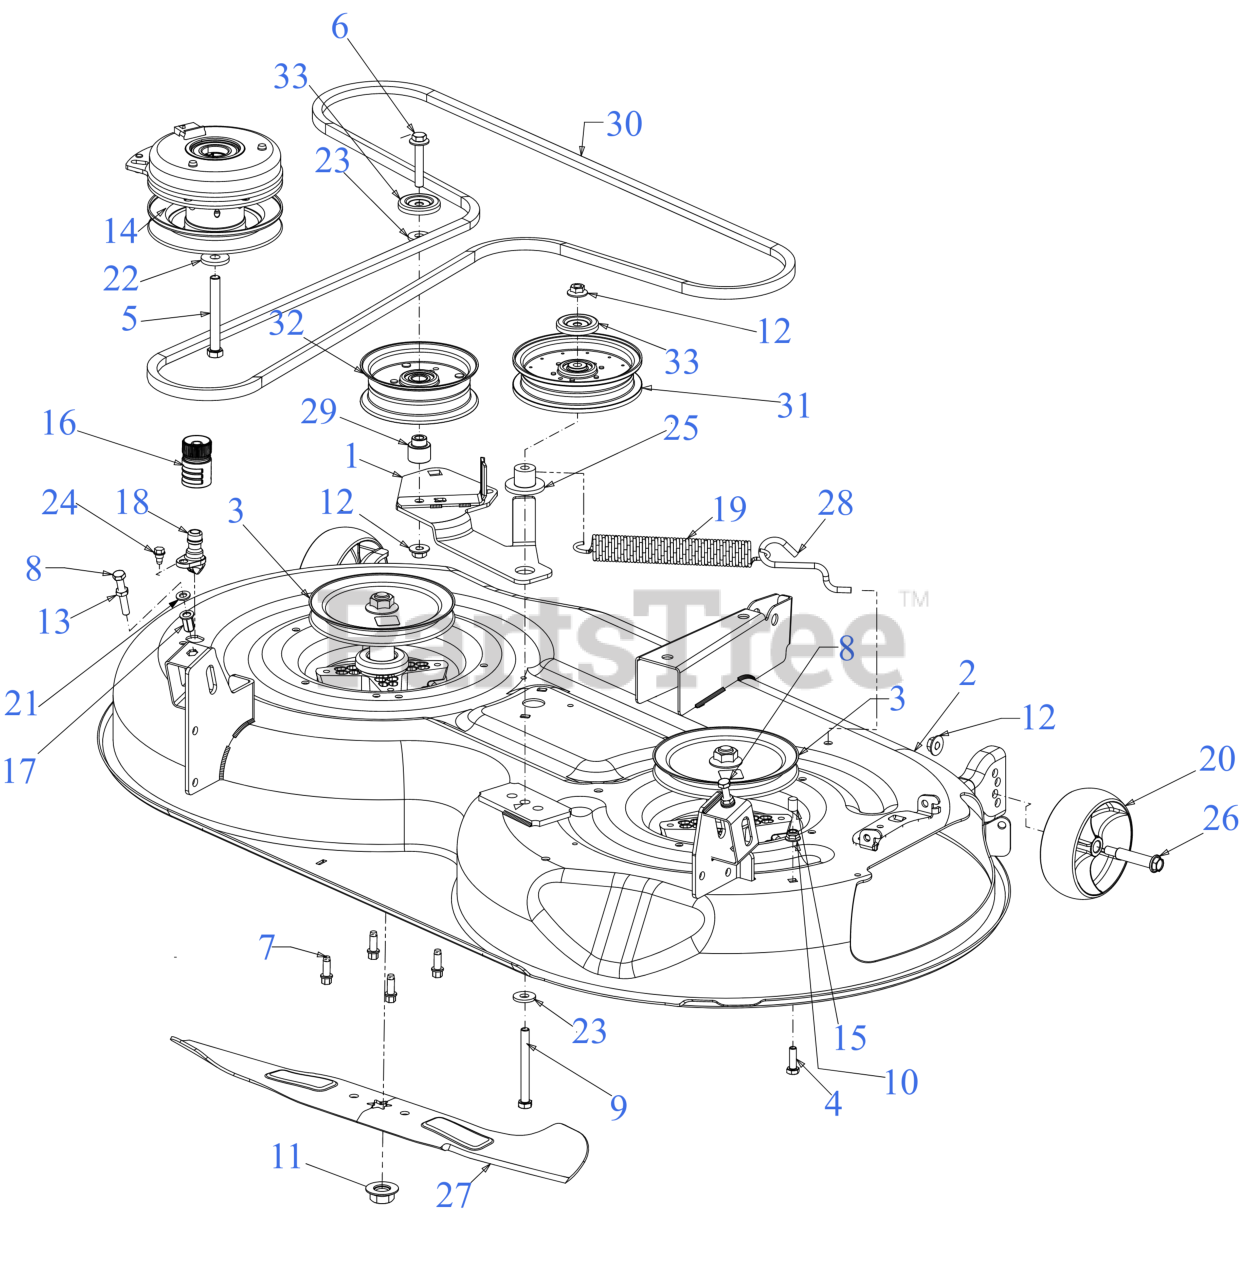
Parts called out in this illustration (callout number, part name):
1	BRACKET ASSEMBLY-DECK IDLER
2	46" DECK SHELL
3	SPINDLE ASSEMBLY
3	Cub Cadet 46" SPINDLE ASSEMBLY (05078A)
4	SCREW 5/16-18 x 1.0 GR5
5	SCREW 7/16-20 x 3.5 GR5
6	SCREW 3/8-16 x 2.25 GR5
7	SCREW 5/16-18 x .875
8	SCREW-FULL THREAD 5/16-18 GR5
9	SCREW 3/8-16 x 3.50 GR5
10	FLANGE LOCK NUT 5/16-18
11	HEX NUT
12	FLANGE LOCK NUT
13	HEX NUT
14	ELECTRIC PTO CLUTCH
15	VINYL CAP
16	WATER NOZZLE ADAPTER
17	NUT RIVET 5/16-18
18	DECK WASH NOZZLE
19	EXTENSION SPRING
20	DECK WHEEL (5.0 DIA x 1.875)
21	FLAT WASHER
22	FLAT WASHER .445 x 1.248 x .170
23	FLAT WASHER .406ID X1.0 OD
24	SHOULDER SCREW 1/4-20 x .50
25	SHOULDER SPACER
26	SHOULDER BOLT (.50 X 2.0 x 3/8 -16)
27	23.25" BLADE (HIGH LIFT)
27	Cub Cadet 46" BLADE SET
27	Genuine Factory Parts 46" HI LIFT BLADE SET
28	DECK SPRING HOOK
29	SHOULDER SPACER
30	V-BELT A SEC x 120.8
30	Cub Cadet 46" RZT DECK BELT
30	Troy-Bilt 46" RZT DECK BELT
31	FLAT IDLER PULLEY
32	IDLER PULLEY 4.50" DIA
33	IDLER PULLEY CAP
